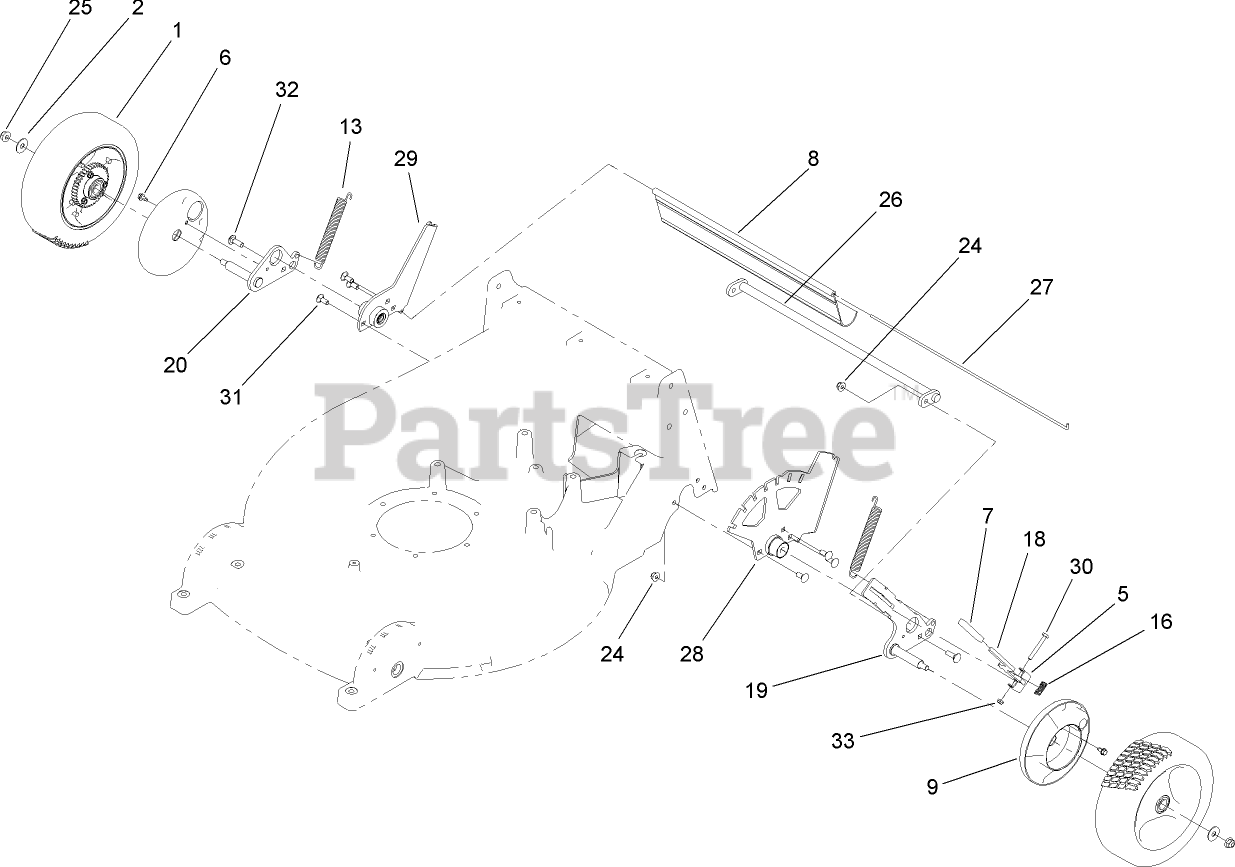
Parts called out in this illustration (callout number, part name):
1	10 INCH WHEEL ASM
2	WASHER
5	BRACKET-PIVOT, LIFT
6	SCREW
7	COVER-HANDLE
8	SHIELD-REAR
9	COVER-GEAR
13	SPRING-ASSIST, LIFT
16	SPRING-LATCH
18	LEVER-LIFT
19	ARM-AXLE, LH
20	ARM-AXLE, RH
24	NUT-HF, NI
25	NUT-HF, NI
26	ROD-TORQUE
27	ROD-SHIELD
28	LH BEARING SUPPORT ASM
29	RH BEARING SUPPORT ASM
30	SCREW-HH
31	BOLT-CARR
32	BOLT-CARR
33	NUT-LOCK, NI
